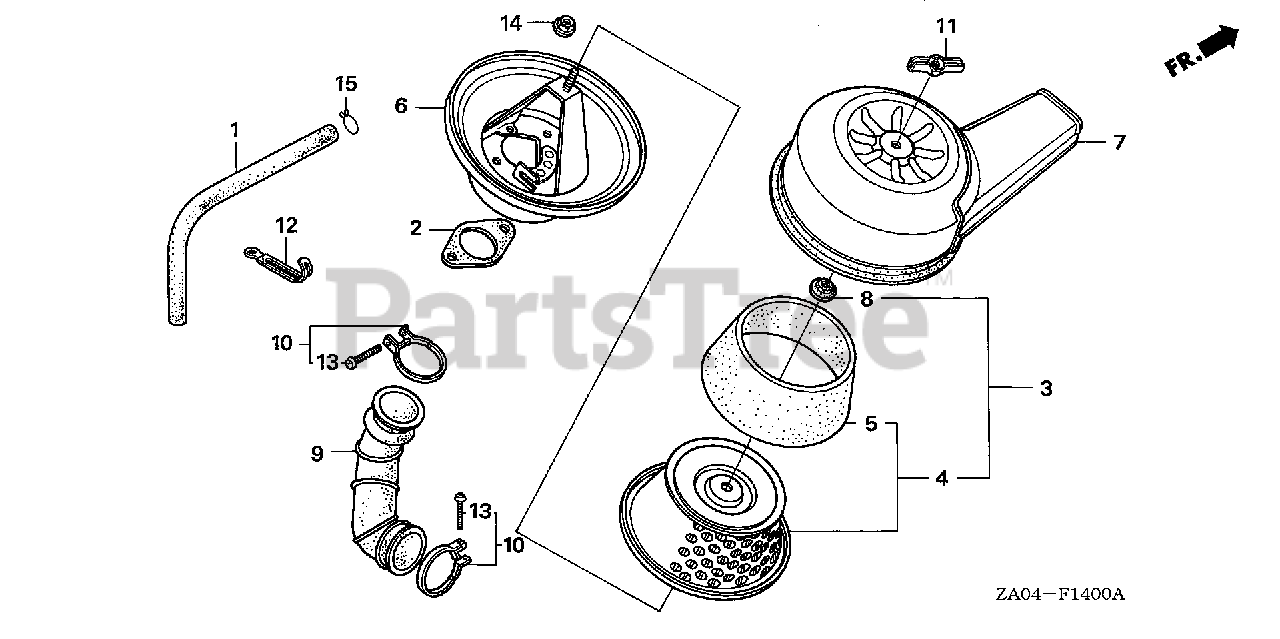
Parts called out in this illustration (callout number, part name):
1	TUBE, BREATHER
2	GASKET, AIR CLEANER
3	ELEMENT, AIR CLEANER
5	FILTER (OUTER)
6	HOUSING, AIR CLEANER
7	COVER, AIR CLEANER
8	GROMMET, AIR CLEANER
9	TUBE, AIR CLEANER CONNECTING
10	BAND, CONNECTING TUBE
11	WINGNUT, AIR CLEANER COVER
12	CLIP (6X20)
13	SCREW, PAN (4X26)
14	NUT, FLANGE (6MM)
15	CLIP, BREATHER TUBE
